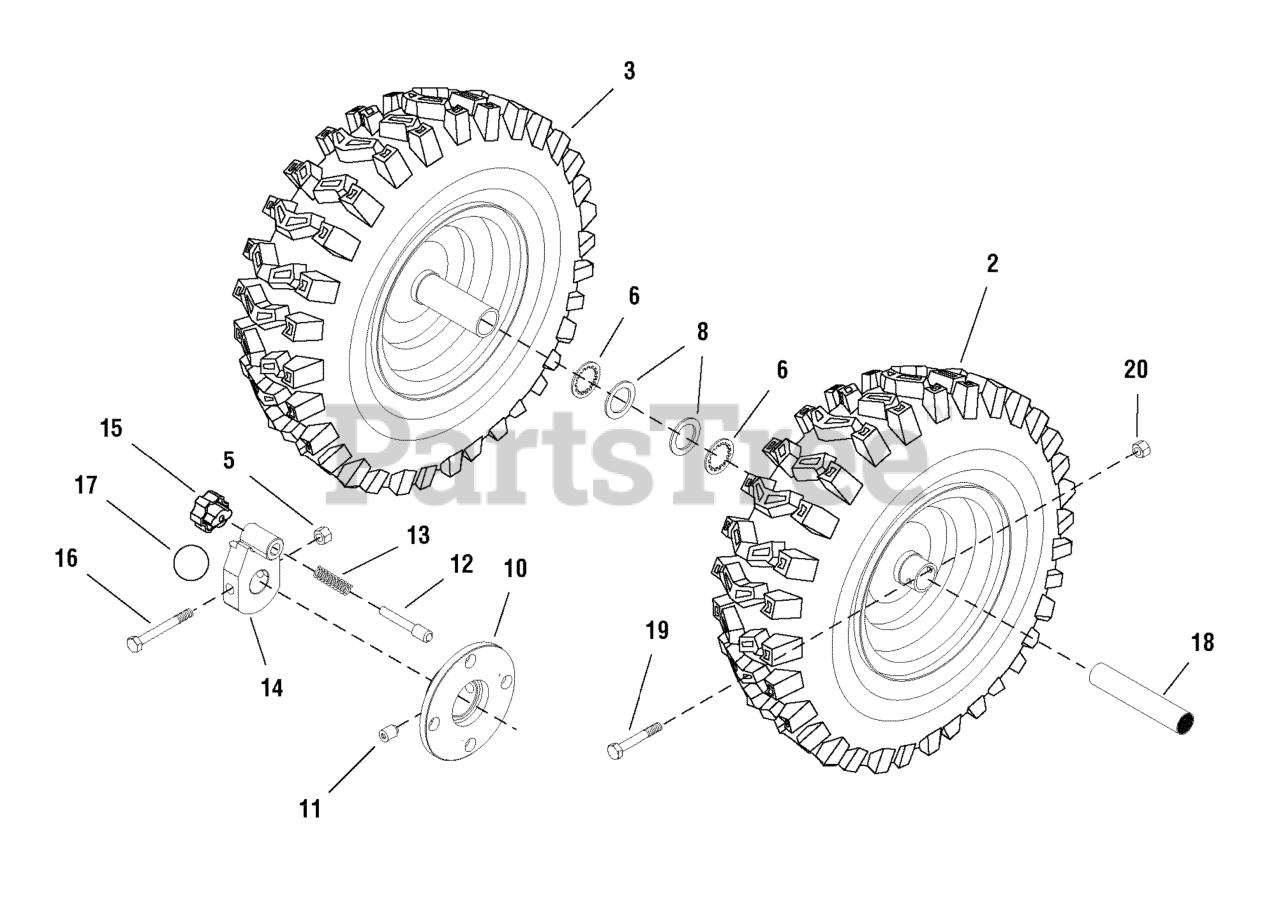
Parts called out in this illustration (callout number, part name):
2	WHEEL & TIRE ASSEMBLY, L.H. SNOW XTRAC 16 x 4.8-8
3	WHEEL & TIRE ASSEMBLY, R.H. SNOW XTRAC 16 x 4.8-8
5	NUT, Hex Lock ESNA Light, 1/4-20 NC3B Black
6	RETAINING RING, Extertal, #75 0.750 Self Lock
8	WASHER, Flat .765 x 1.12 x .06 YZ
10	DISC, Wheel Lock
11	SCREW, 3/8-16 x 1/2 Hex-18
12	PIN, Wheel Lock 1/4-20 0.7
13	SPRING, Compression
14	HUB, Wheel Lock Centered
15	KNOB, Wheel Lock
16	CAPSCREW, 1/4-20 x 2-1/4 Hex Head GR
17	DECAL, WHEEL LOCK
18	BUSHING, WHEEL
19	BOLT, .25-20 X 1.75
20	NUT, 1/4-20 HEX NYLOCK
